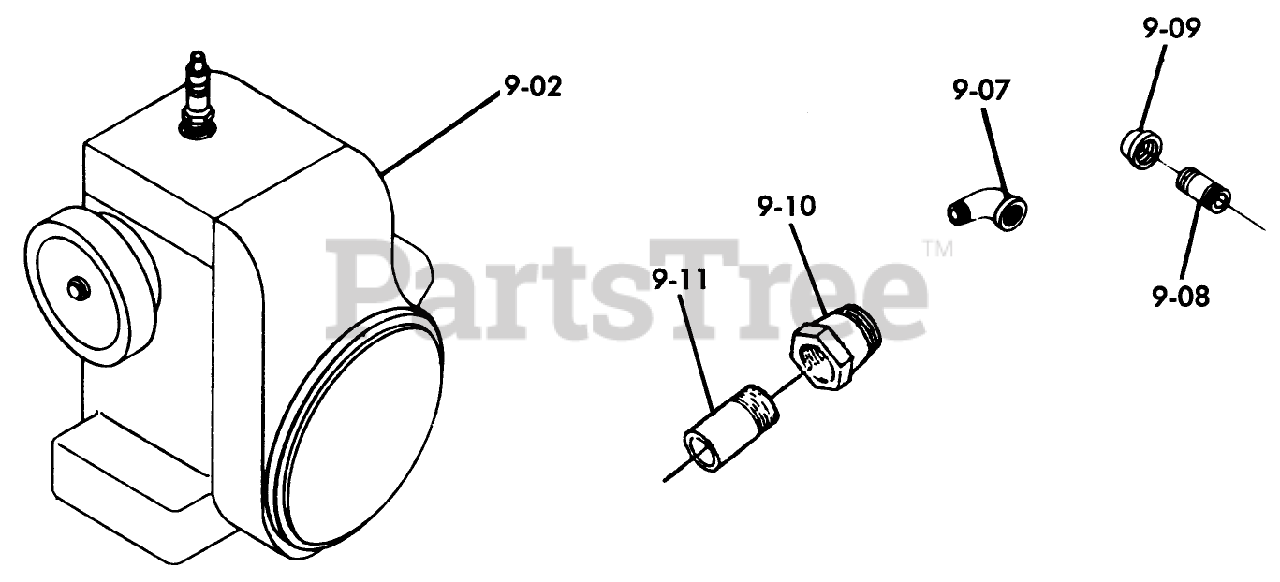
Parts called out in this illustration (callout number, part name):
9-02	Engine-12HP Kohler
9-07	ELBOW-STREET
9-08	Nipple 3/8 x 5
9-09	Cap
9-10	REDUCER 1 1/4-1
9-11	NIPPLE
